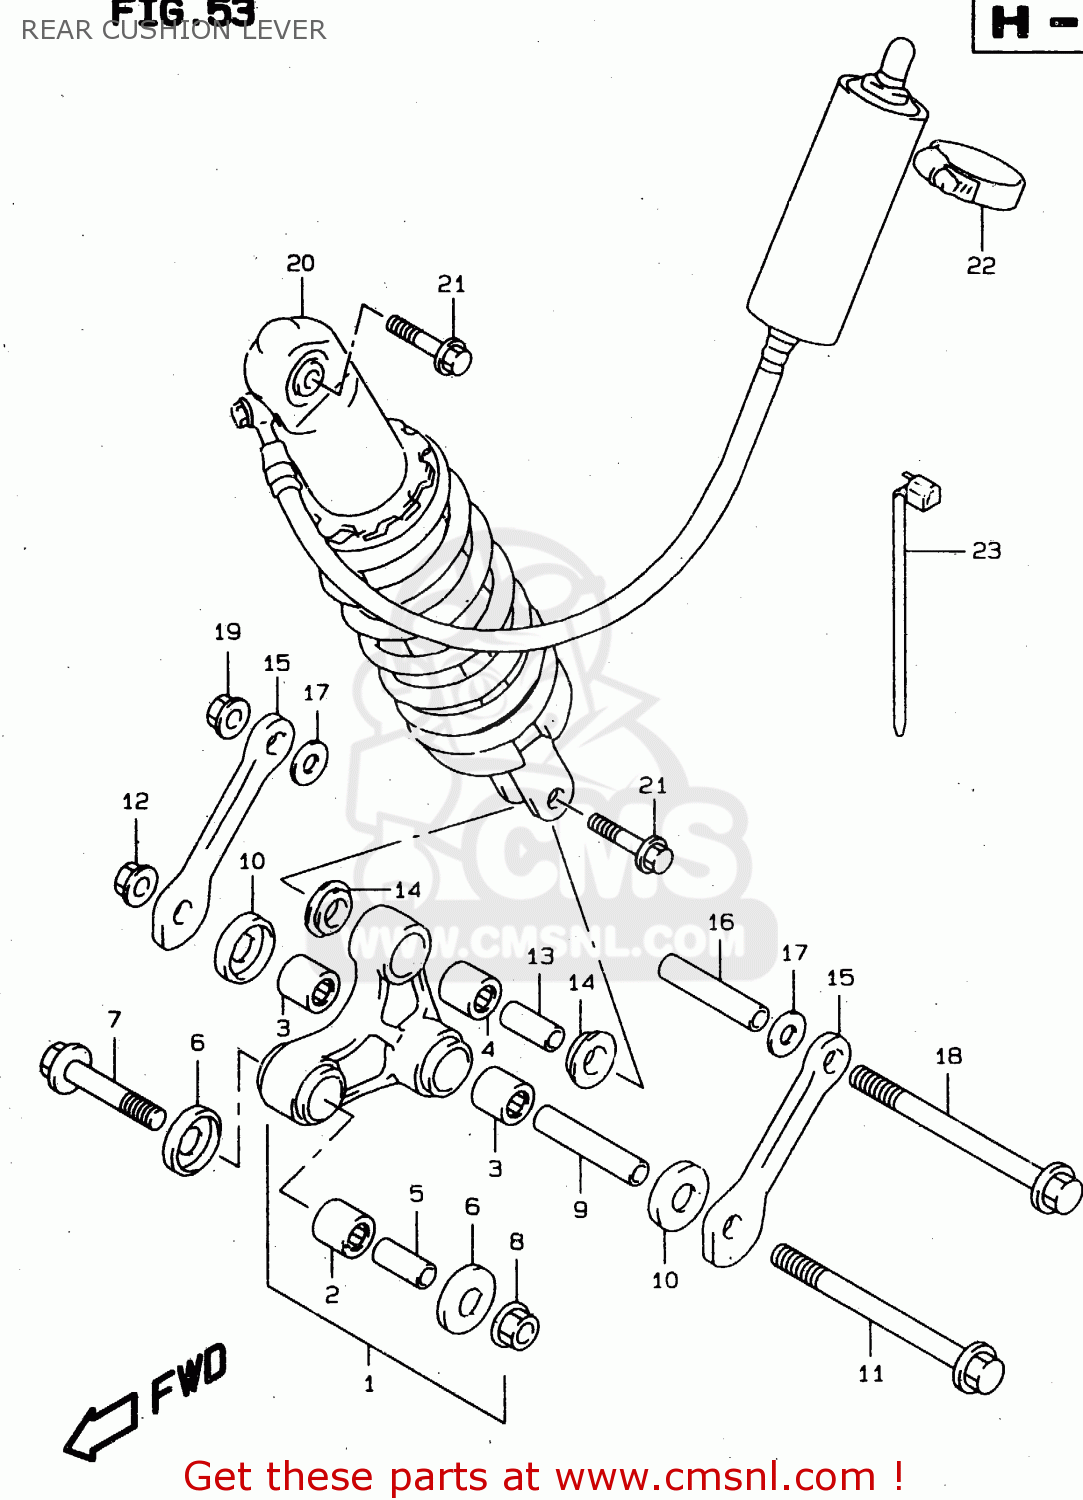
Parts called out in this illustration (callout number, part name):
1	LEVER SET,RR CUSHION
2	BEARING(20X27X30)
3	BEARING(21X27X20)
4	BEARING(17X24X20)
5	SPACER,RR CUSHION LEVER FR
6	SEAL,RR CUSHION LEVER FR DUST
7	BOLT,RR CUSHION LEVER FR
8	NUT 12MM
9	SPACER,RR CUSHION LEVER CTR
10	SEAL,RR CUSHION LEVER CTR
11	BOLT,RR CUSHION LEVER CTR
12	NUT
13	SPACER,RR CUSHION LEVER
14	SEAL,RR CUSHION LEVER RR DUST
15	ROD,RR CUSHION LEVER
16	SPACER,RR CUSHION LEVER CTR
17	WASHER
18	SHAFT,RR CUSHION LEVER FR
19	NUT
20	ABSORBER ASSY, REAR SHOCK
21	BOLT,RR CUSHION ROD UPR
22	CLAMP
23	CLAMP(L:125)
